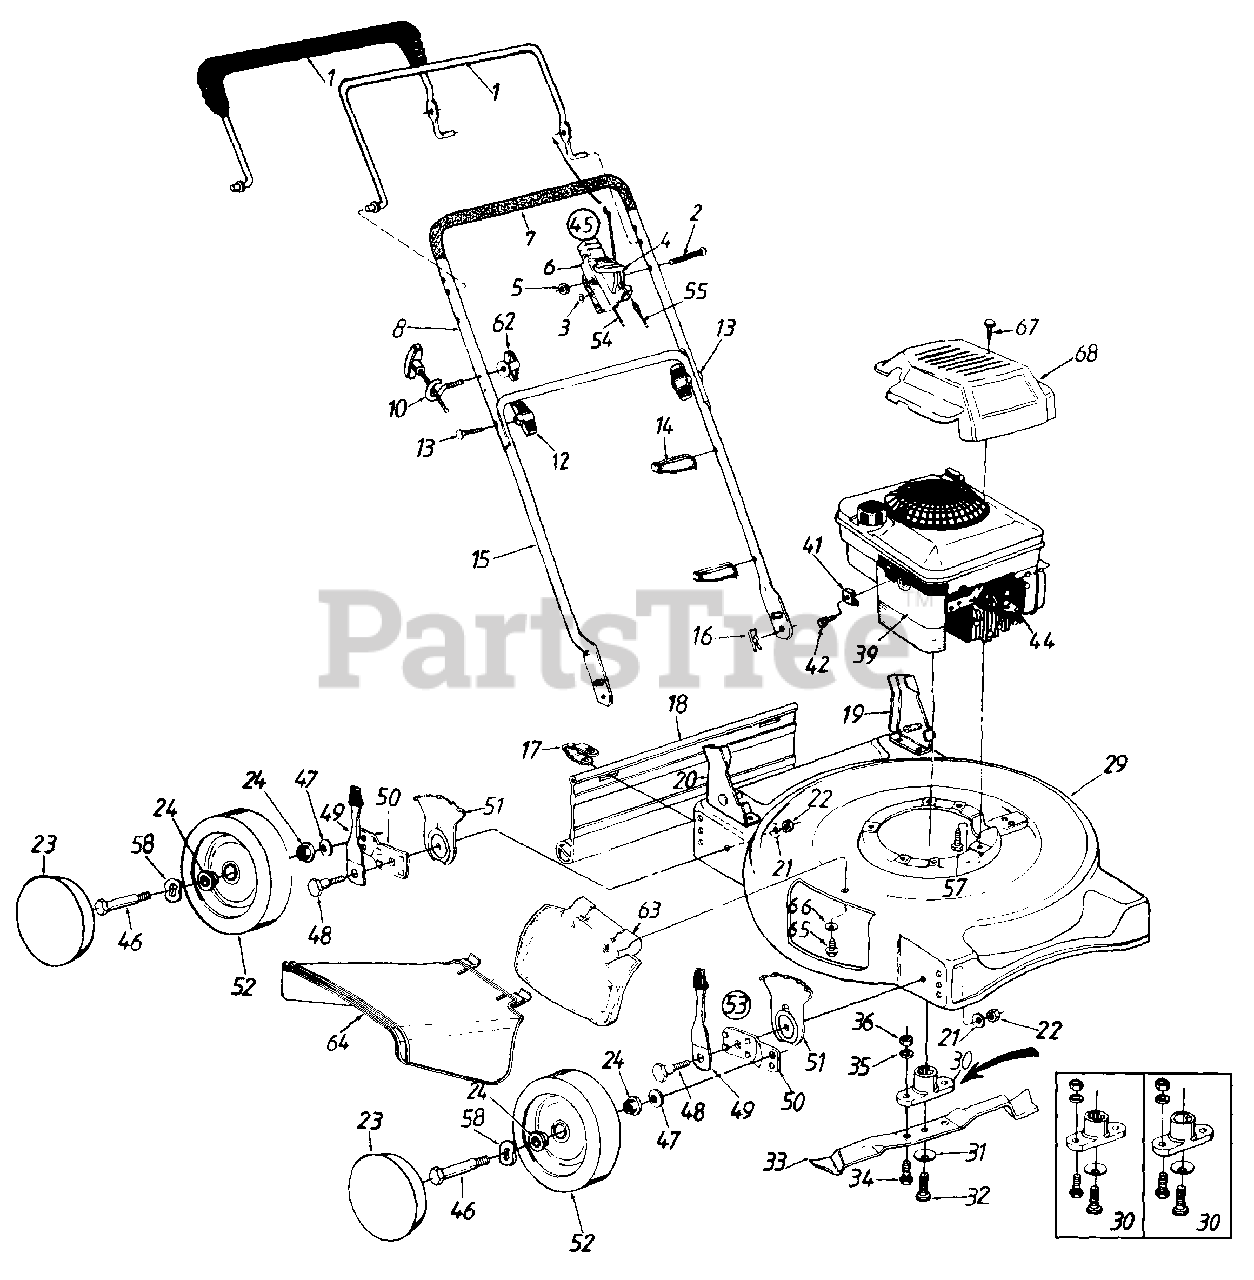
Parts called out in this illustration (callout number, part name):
1	Control Handle Ass'y. (Deluxe)
2	Oval C-Sunk Scr.
3	Spr. Wash..66" I.D.
4	Throttle Lever
5	Hex L-Nut 1/4-20 Thd.
6	Throttle Body
7	Grip
12	Hand Knob
13	Curved Hd. Bolt 5/16-18 x 2" Lg.
14	Cable Tie
16	Hairpin Cotter
17	Hinge Clip
18	Rear Flap
22	Hex Nut 3/8-16 Thd.
23	Hub Cap
24	Bearing
29	20" Deck Ass'y.
30	Blade Adapter Kit (Keyed)
31	Bell-Wash..39" I.D.
32	Hex Bolt 3/8-24 x 1.5" Lg.
33	20" Mulching Blade
34	Hex Bolt 3/8-24 x 1" Lg.
35	L-Wash. 3/8" I.D.
36	Hex Nut 3/8-24 Thd.
39	Engine
41	Cable Clamp (B & S)
42	Hex Self-Tap Scr. #10-32 x .62" (B&S)
44	Spark Plug Boot
46	Axle Bolt
47	Bell-Wash..400" I D. x .88"
48	Shld. Bolt .50" Dia. x .357"
49	Spring Lever Ass'y. w/Knob
51	Height Adj. Plate
52	Wheel Ass'y. Comp.
53	Height Adj. Ass'y. Comp.- R.F. 8 L.R.
54	Throttle Cable - 51" (B & S)
55	Control Cable - 39" (B&S)
57	Hex L-Wash. Hd. Scr. 3/8-16 x 1.0" Lg.
58	Wave Washer .51" I.D.
62	Handle Knob 1/4-20 Thd.
63	Mulching Plug
64	Chute Deflector
65	Bell-Wash. 1/4" I.D.
66	Hex Wash. Hd TT-Tap Scr. 1/4-20 x .5" Lg.
67	Hi-Lo Scr. #10 x 1.25" Lg.
68	Engine Shroud (Black)
